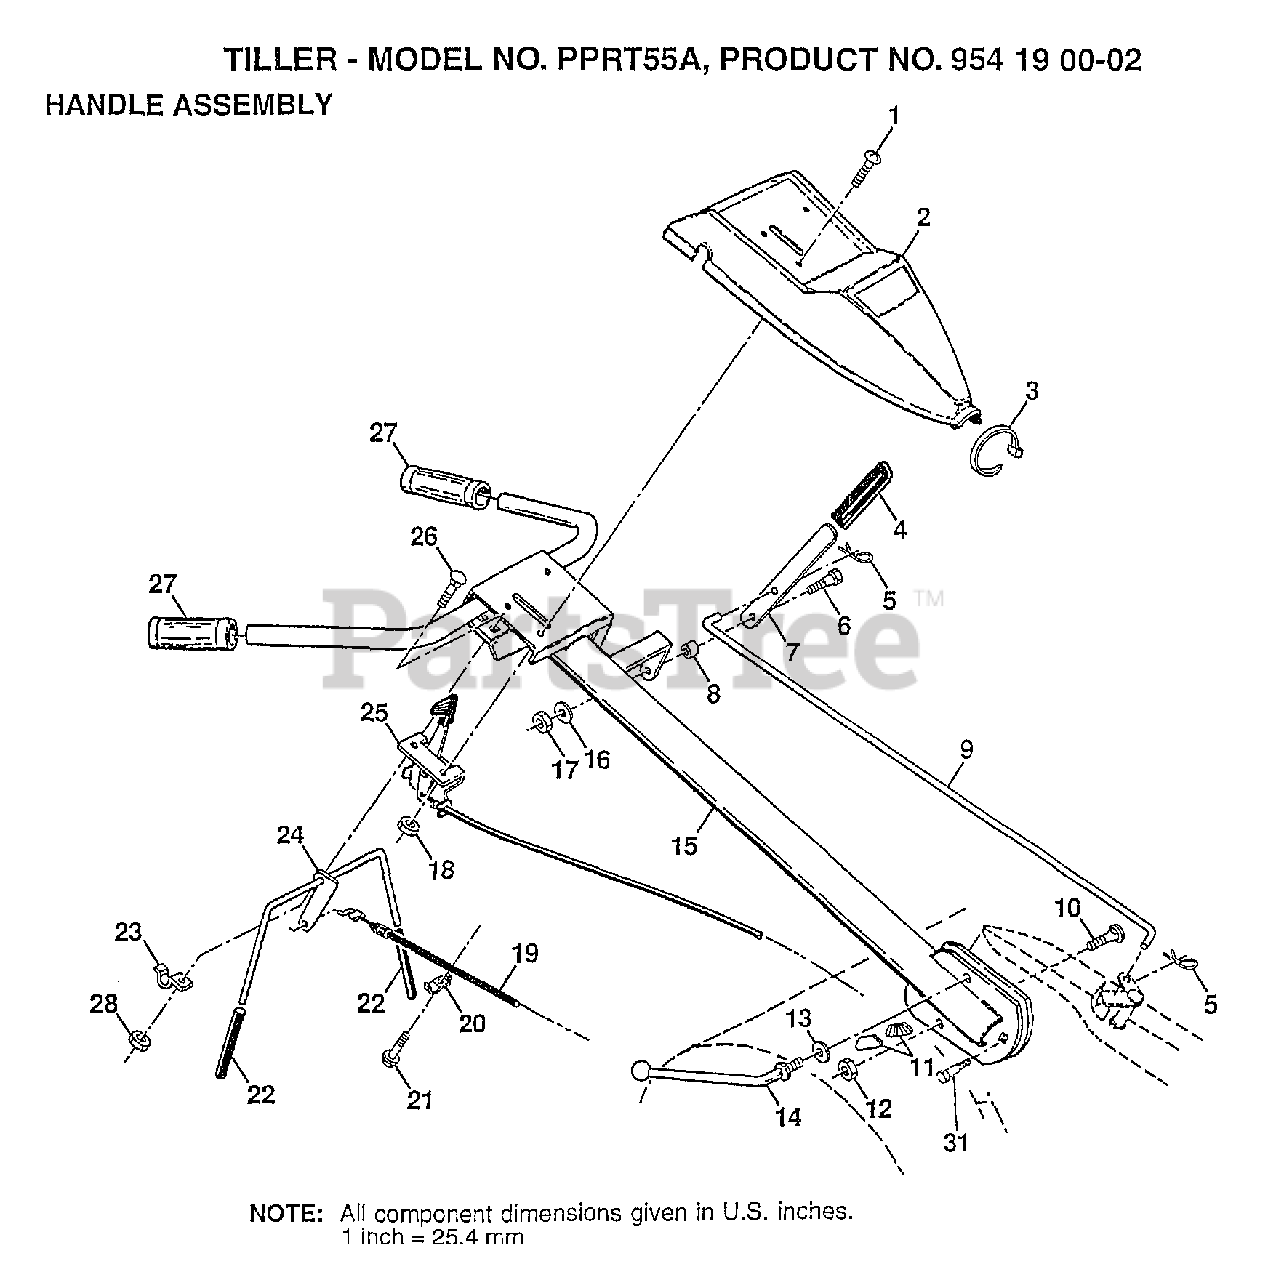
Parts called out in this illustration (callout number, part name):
1	SCREW.PNHD.10-24
2	PANEL, CONTROL
6	SHOULDER BOLT ST
8	GROMMET, RUBBER
10	BOLT D
11	LOCK, HANDLE
12	LOCKNUT
13	WASHER CRT
14	LEVER, LOCK HANDLE
16	LOCKWASHER
19	CABLE.CLUTCH.48.Z
20	CONDIUT CLIP T
22	GRIP BAR CONTROL
23	CLAMP BAR CONTROL
24	BAR ASSEMBLY CONTROL
25	CONTROL THROTTLE
26	BOLT
28	NUT
31	BOLT PIVOT
